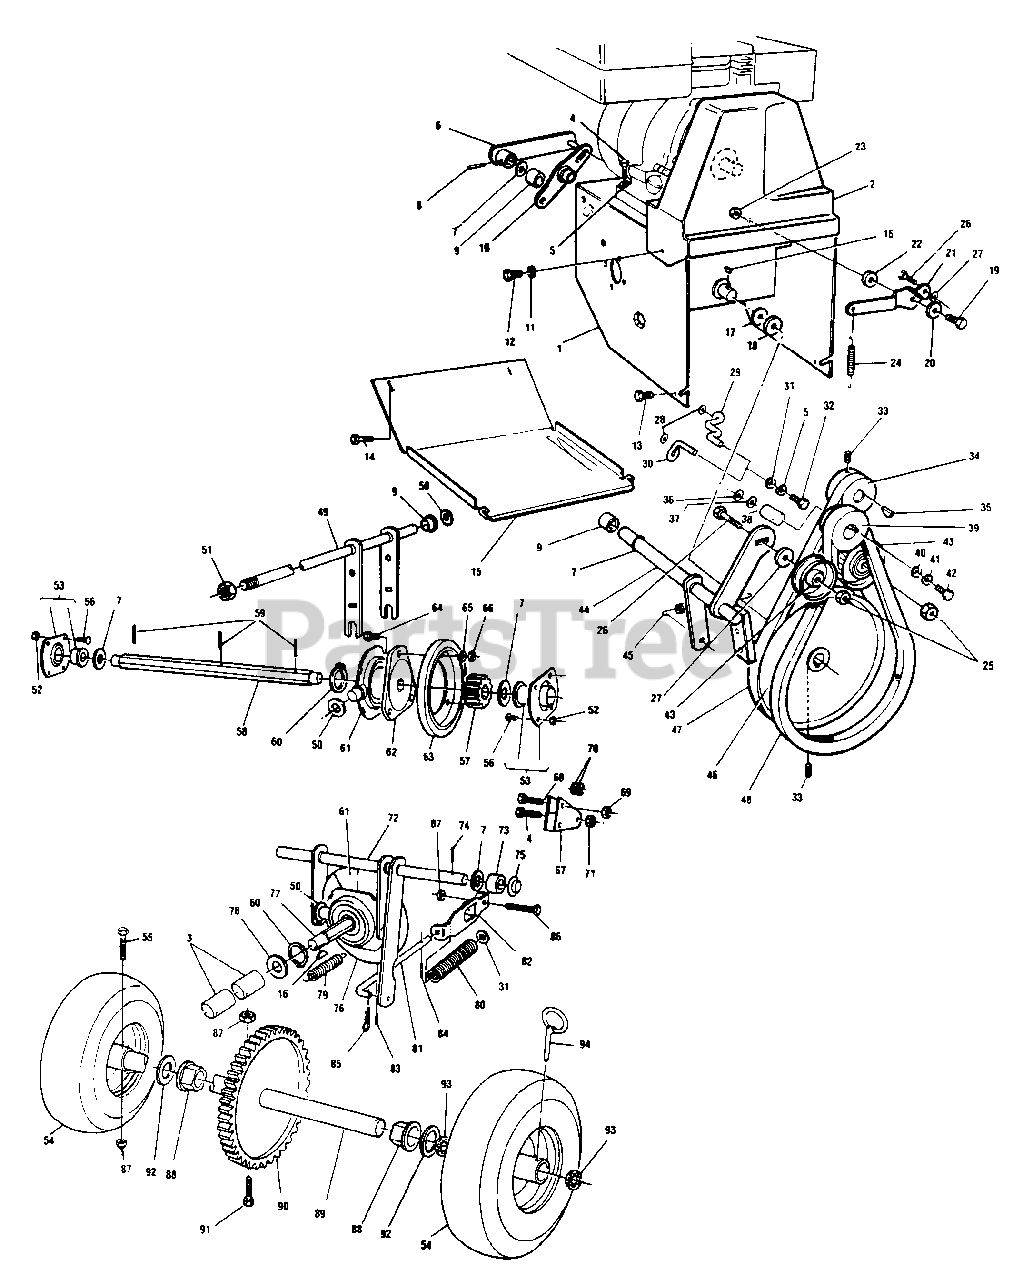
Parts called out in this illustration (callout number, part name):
1	FRAME - Motor Mount (red)
2	BELT - Cover
3	BEARING - Needle
4	BOLT - 5/16-18 x 1 1/4
5	WASHER - Lock 5/16
6	LEVER - Auger Clutch
7	WASHER - Flat 17/32
8	PIN - Roll 5/32 x 7/8
9	BUSHING - Plastic
10	LEVER - Clutch Cable
11	WASHER - Flat 1/4
12	SCREW - Self Tapping 1/4-20 x 1/2
13	SCREW - Self Tapping 5/16-18 x 1/2
14	SCREW - Self Tapping 1/4-20 x 1/2
15	PANEL - Bottom
16	KEY - Hypro 3/16
18	RACE THRUST
19	BOLT 5/16-18 x 3/4
20	WASHER - 5/16-1 3/8 x 14 GA
21	LEVER - Idler Traction
22	BUSHING - Idler
23	NUT - Lock 5/16-18
24	SPRING - Idler
25	NUT - Hex Jam 3/8-16
26	BOLT - 3/8-16 x 1 1/4
27	WASHER - Flat 3/8
28	RETAINER - Spacer Belt
29	BELT - Guide (L.H.)
30	BELT - Guide (R.H.)
31	WASHER - Flat 5/16
32	BOLT - 5/16-24 x 1
33	SCREW - Set 5/16-18 x 1/2
34	PULLEY - PTO
35	KEY - No. 5
36	WASHER - Race Thrust
39	PULLEY - Auger Drive
41	WASHER - Lock
42	BOLT - 3/8-24 x 1
43	PULLEY - 2" Idler
44	ROD - Auger Clutch
46	PULLEY - 8" Traction
47	BELT - Traction Drive
48	BELT - Auger Drive
49	SHAFT - Speed Control
51	NUT - Lock 3/8-16
52	NUT - Keps 10-24
53	BEARING ASSEMBLY
54	WHEEL - 4-10 x 3-50-4
55	BOLT - 1/4-20 x 1 1/2 Gr. 5
56	BOLT - Carriage 10-24 x 3/8
57	PINION - 8 Tooth
58	SHAFT - Hex
59	PIN - Roll 1/8 x 3/4
60	RING -Snap 1 1/4
61	TRUNION BEARING ASSEMBLY
62	WHEEL - Hub Friction
63	WHEEL - Friction
64	BOLT - 1/4-20 x 5/8
65	WASHER - Lock 1/4
66	NUT - Hex 1/4-20
67	PIVOT TRACTION
68	BOLT - 1/4-20 x 1 3/4
69	NUT - Lock 1/4-20
71	NUT - Lock 5/16-18
72	TRACTION SHAFT ASSEMBLY
74	PIN - Cotter 1/8 x 1
75	NUT - Push 1/2
76	DRIVE - Disc
77	SHAFT - Traction Hex
78	BEARING - Thrust
80	SPRING - Traction
81	ROD - Traction
82	BRACKET - Traction Spring
83	PIN - Spring 1/8 x 1 3/8
84	PIN - Spring 1/8 x 1/2
85	PIN - Cotter 3/32 x 3/4
86	BOLT - 1/4-20 x 1 1/4
87	NUT - Lock 1/4-20
88	BEARING - Axle
90	GEAR - 48 Tooth
91	BOLT - 1/4-20 x 2 3/4
93	RING - Grip
94	PIN - Clik
